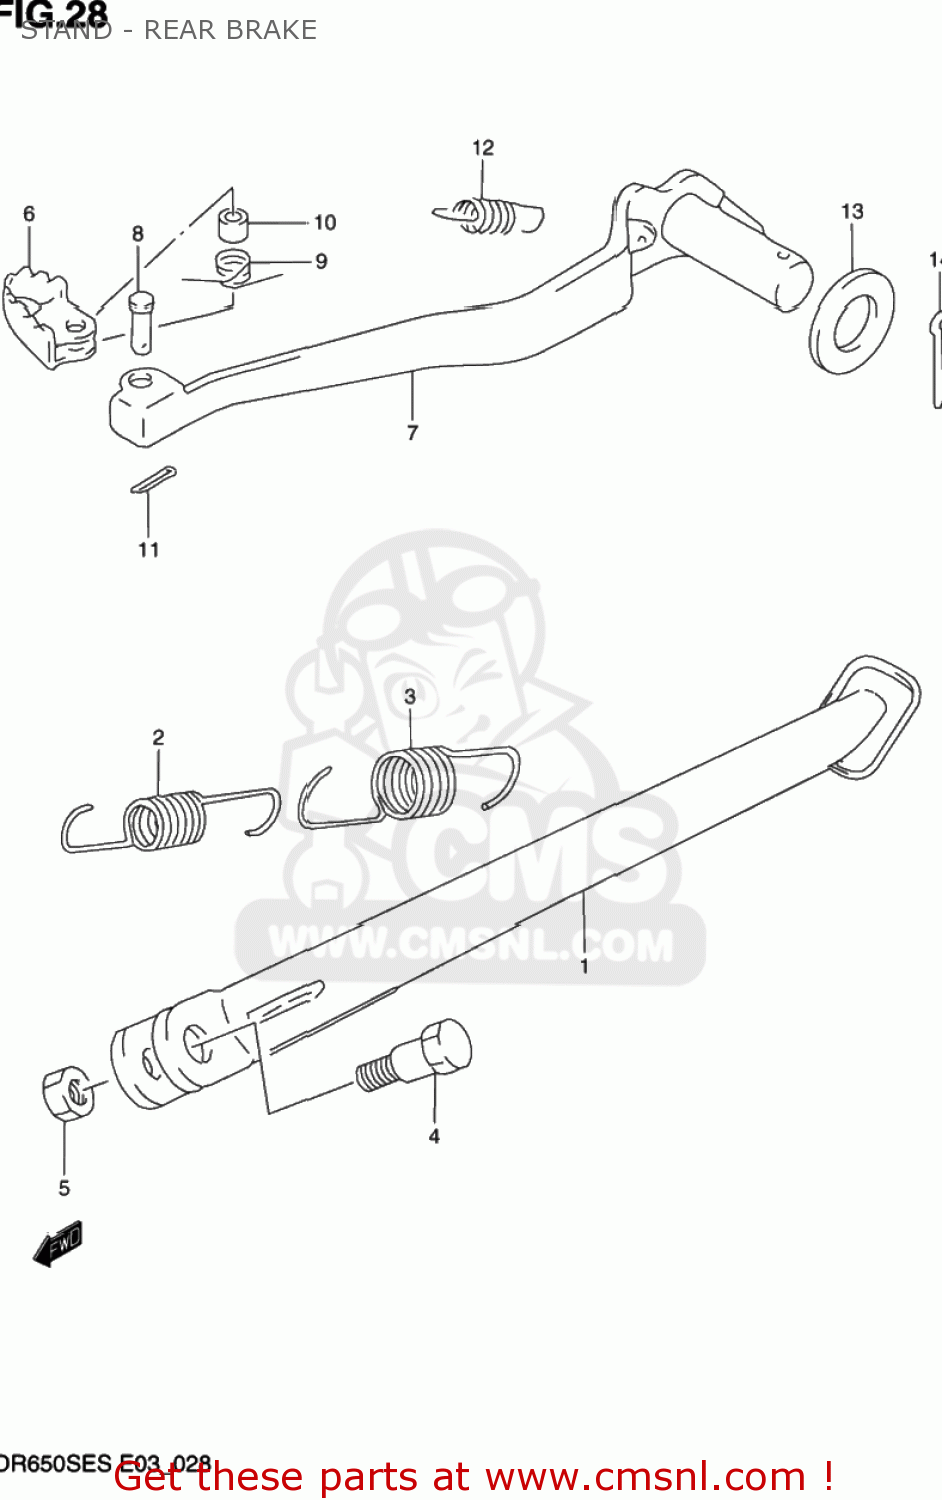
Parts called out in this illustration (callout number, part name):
1	STAND,PROP(BLACK)
2	SPRING
3	SPRING
4	BOLT(10X30)
5	NUT
6	PEDAL,BRAKE
7	ARM,BRAKE PEDAL
8	PIN
9	SPRING
10	SPACER(9.2X9X6.5)
11	PIN
12	SPRING
13	WASHER (17.6X34X2)
14	COTTER PIN
